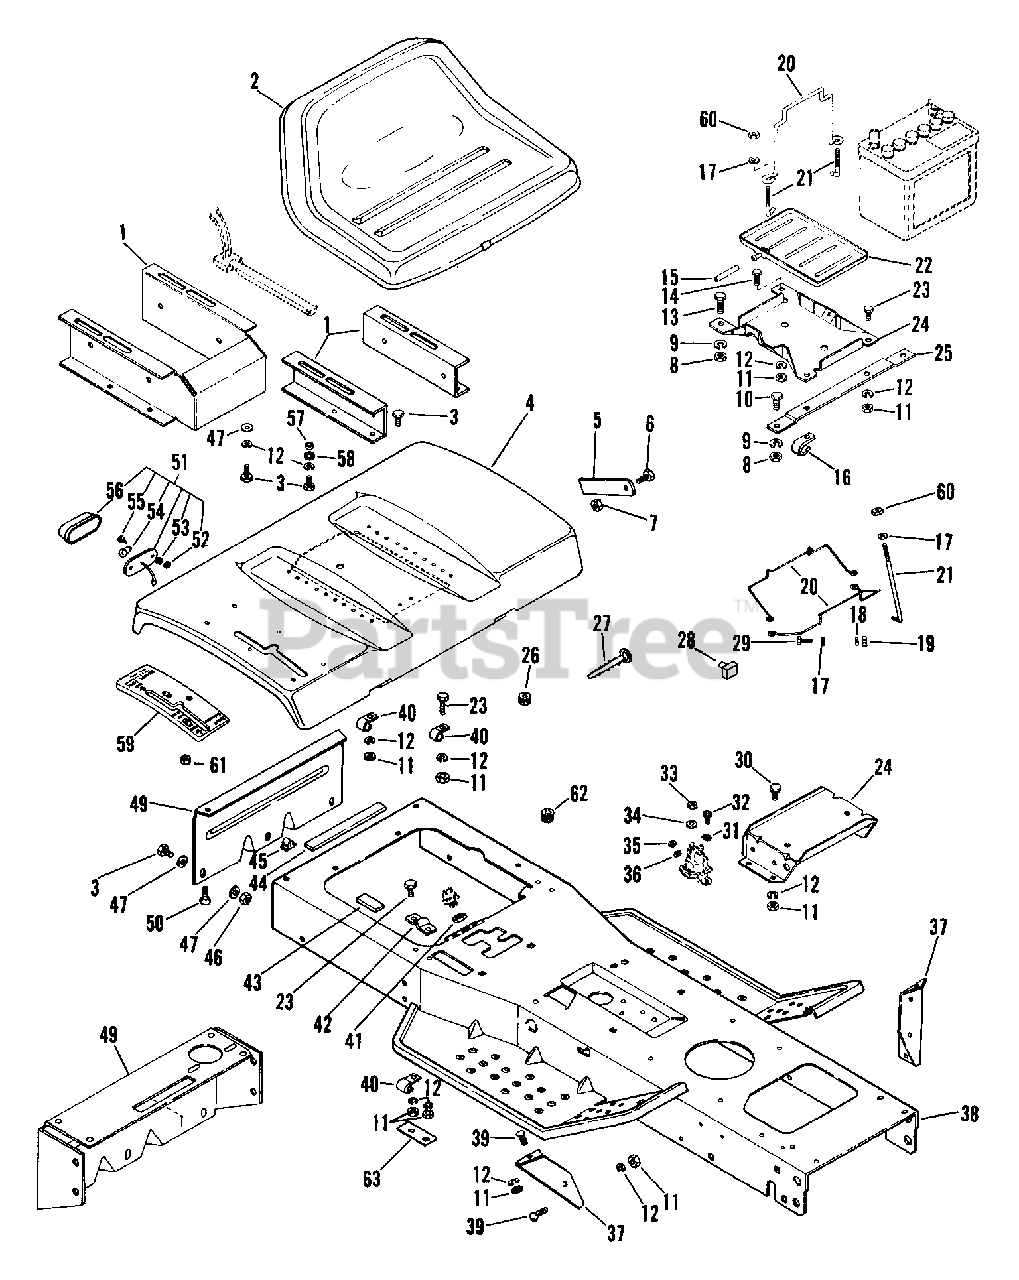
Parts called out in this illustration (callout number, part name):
1	SEAT CHANNEL R H
1	SEAT CHANNEL L H
1	SEAT FRAME
2	SEAT V-350
3	BLT-HEX .31-18X.75 PL GR5
4	REAR DECK
5	CATCH,DECK
6	BLT-HEX .38-16X.63 PL GR2
7	NUT-LK-JAM-CTR .375-16 PL
8	NUT-HEX .375-16
9	WSHR-LK .375X.115 HVY PL
10	BLT-HEX .38-16X.75 PL GR2
11	NUT-HEX .312-18
12	WSHR-LK .312X.097 PL HVY
13	BLT-HEX .38-16X1.25 PL GR 2
14	BLT-HEX .31-18X1.00 PL GR 2
15	DRAIN HOSE
16	J-CLAMP
17	WSHR-FL-STL.281X.62X.065 PL
18	WSHR-LK .250X.077 HVY PL
19	NUT-HEX .250-20 PL
20	HOLD DOWN
20	BATTERY HOLD DOWN
21	TIE DOWN
22	BATTERY TRAY
23	BLT-HEX .31-18X.75 PL GR2
23	SCR-TAP .312-18X.50 HWH PL TR
24	BATTERY STAND
24	BATTERY TRAY
25	STRAP
26	GROMMET, .31 ID
26	GROMMET 1.0ID X 1.38 OD
27	TIE DOWN
28	INSULATOR
29	BLT-HEX .25-20X.75 PL GR2
30	BLT-HEX .31-18X.63 PL GR 2
31	WSHR-LK-EXT. 250 ID
32	SCR-TAP .250-20X.37 HWH PL TR
33	NUT-JAM .312-24 PL
34	WSHR-LK-INT .313X.030 PL
35	NUT 10-32 PL
36	WSHR-LK-EXT #10 ID X .022
37	STRUT LEFT FOOT BOARD
37	STRUT RIGHT FOOT BOARD
38	FRAME W/DECALS
38	MAIN FRAME
39	BLT-RDHDSQNK .31-18X.75 SHT PL
40	J-CLAMP
41	NUT- .562-18
43	FOAM TAPE
44	FOAM TAPE
46	NUT-LK-TOP .312-18 GR C PL
47	WSHR-FL-STL .38X.875X.083 PL
48	NUT-LK-CTR .375-16 GR A PL
49	DRAW BAR
50	BLT-HEX .38-16X1.25 PL GR5
51	TAIL LIGHT ASSEMBLY W/BULLET
52	NUT-HEX 10-24 PL
53	WSHR-LK 10X.047 MED PL
55	SCR-MCH 10-24X.50 SLTR PL
56	TAIL LIGHT LENS
57	SPACER BUSHING .5 X .32 X .21
58	WSHR-FL-STL .505X.875X.024 PL
59	SHIFT INSERT
60	NUT-LK-NYL .250-20 PL
61	NUT-SELF-THRDNG FITS.25 STUDPL
62	HOLE PLUG
